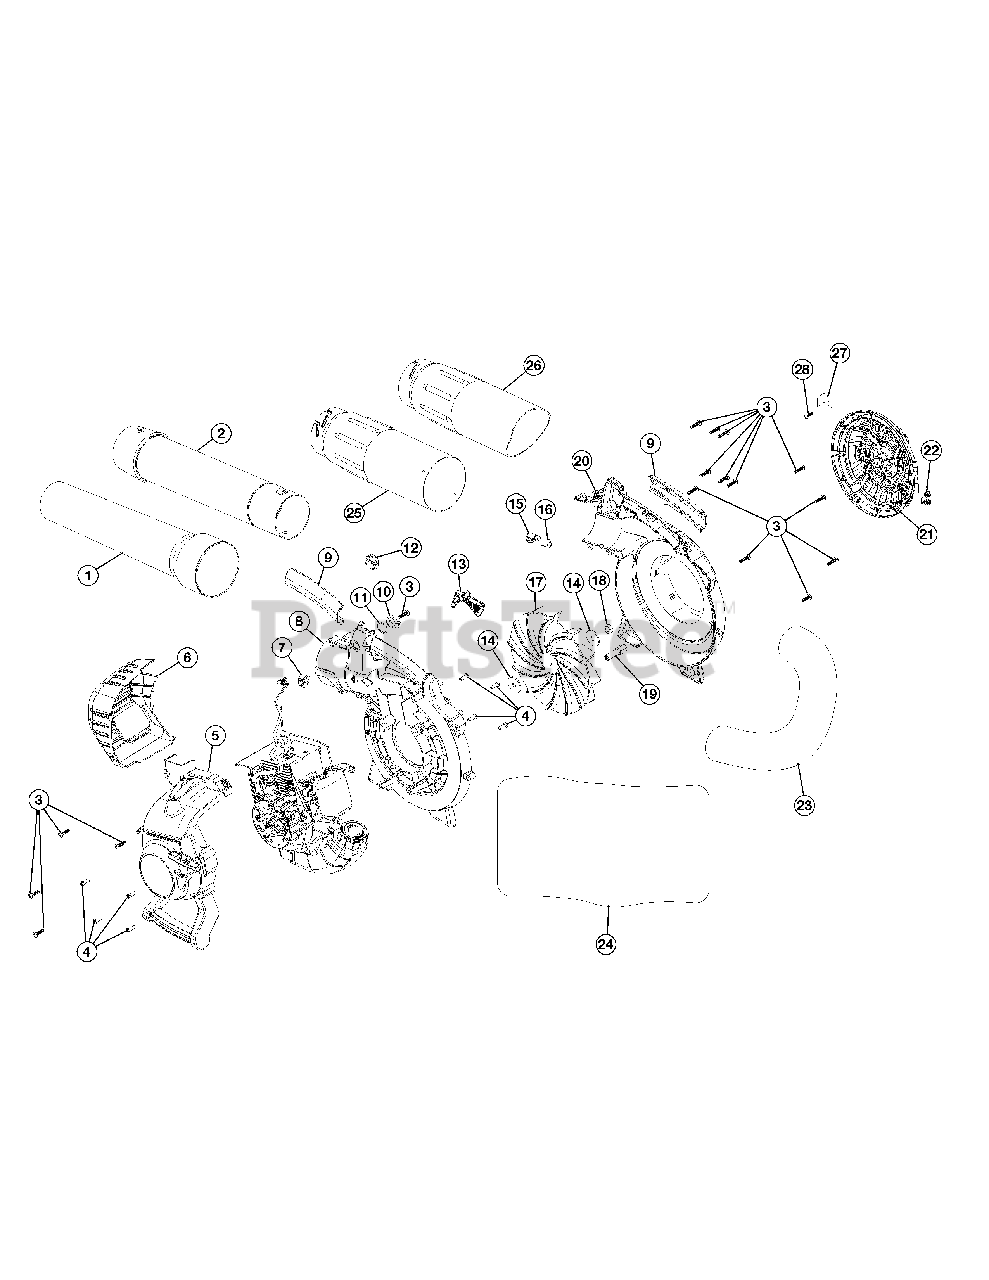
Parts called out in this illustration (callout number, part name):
1	Lower Tube
2	Upper Tube
4	Screw
5	Engine Cover Assembly (Incl. 3 & 4)
6	Muffler Cover Assembly (Incl. 3)
7	Outer Trigger Lock
8	Impeller Housing
9	Handle Grips
10	Inner Trigger Lock
11	Wavey Washer
13	Throttle Trigger
14	Washer
15	Latch Tube
16	Latch Spring
17	Impeller
18	Nut
19	Adapter
20	Impeller Housing
21	Intake Cover
22	Spring
25	Upper Vac Tube
26	Lower Vac Tube
27	Door Lock
28	Screw
